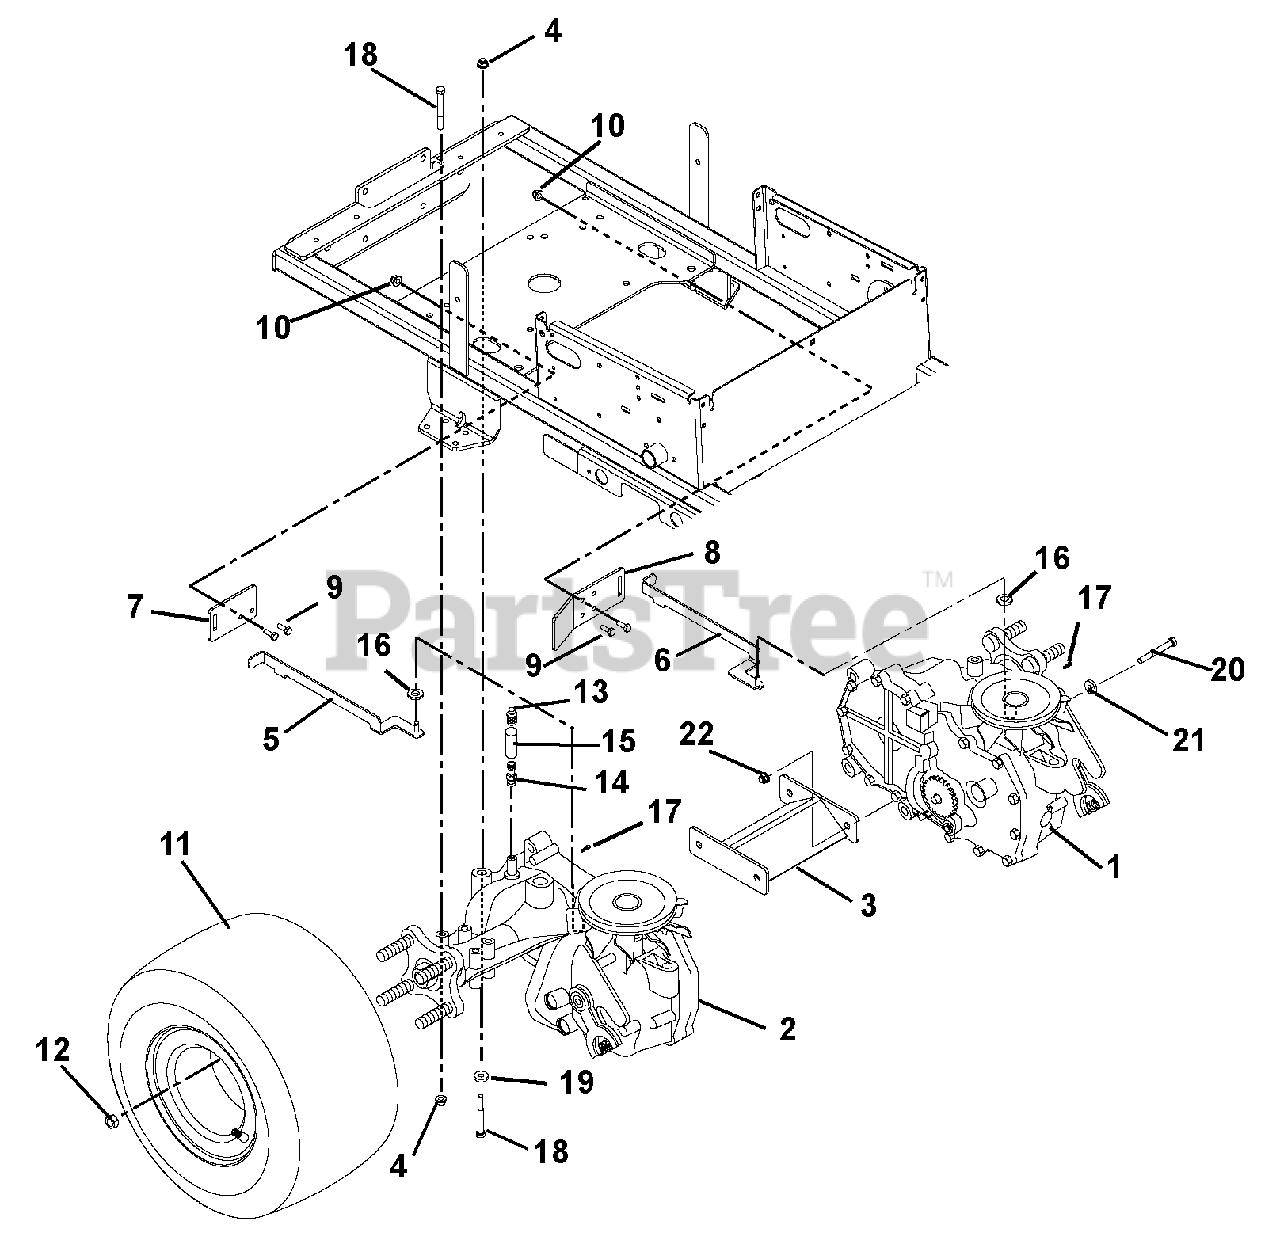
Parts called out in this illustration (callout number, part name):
1	EZT, Left Hand Transaxle-Hydrogear (For service please contact Hydro-Gear)
2	EZT, Right Hand Transaxle-Hydrogear (For service please contact Hydro-Gear)
3	Weldment, Transaxle Support
4	Nut .31-18 Flange Nyloc
5	Weldment, Dump Valve (RH)
6	Weldment, Dump Valve (LH)
7	Bracket, Dump Valve
8	Clutch Stop
9	Bolt, Hex .25-20 x .75 Grade 5
10	Nut, Locking Nylon .250-20
11	Tire/Wheel Assembly 18 x 6.50-8 Center
12	Nut, Lug .50-20
13	Cap, Vent .50
14	Fitting, Straight .50
15	Hose, Vent
16	Washer, Flat-Steel .265 x .50 x .087
17	Pin, Hair-Internal .06 x .18 x .77
18	Bolt, Hex .31-18 x 2.75
19	Washer, Flat Steel .328 x .87 x .179
20	Bolt, Hex .38-16 x 2.50 Grade 5
21	Washer, Flat Steel .406 x 1.00 x .188
22	Nut, .38-16 Nyloc Flange
